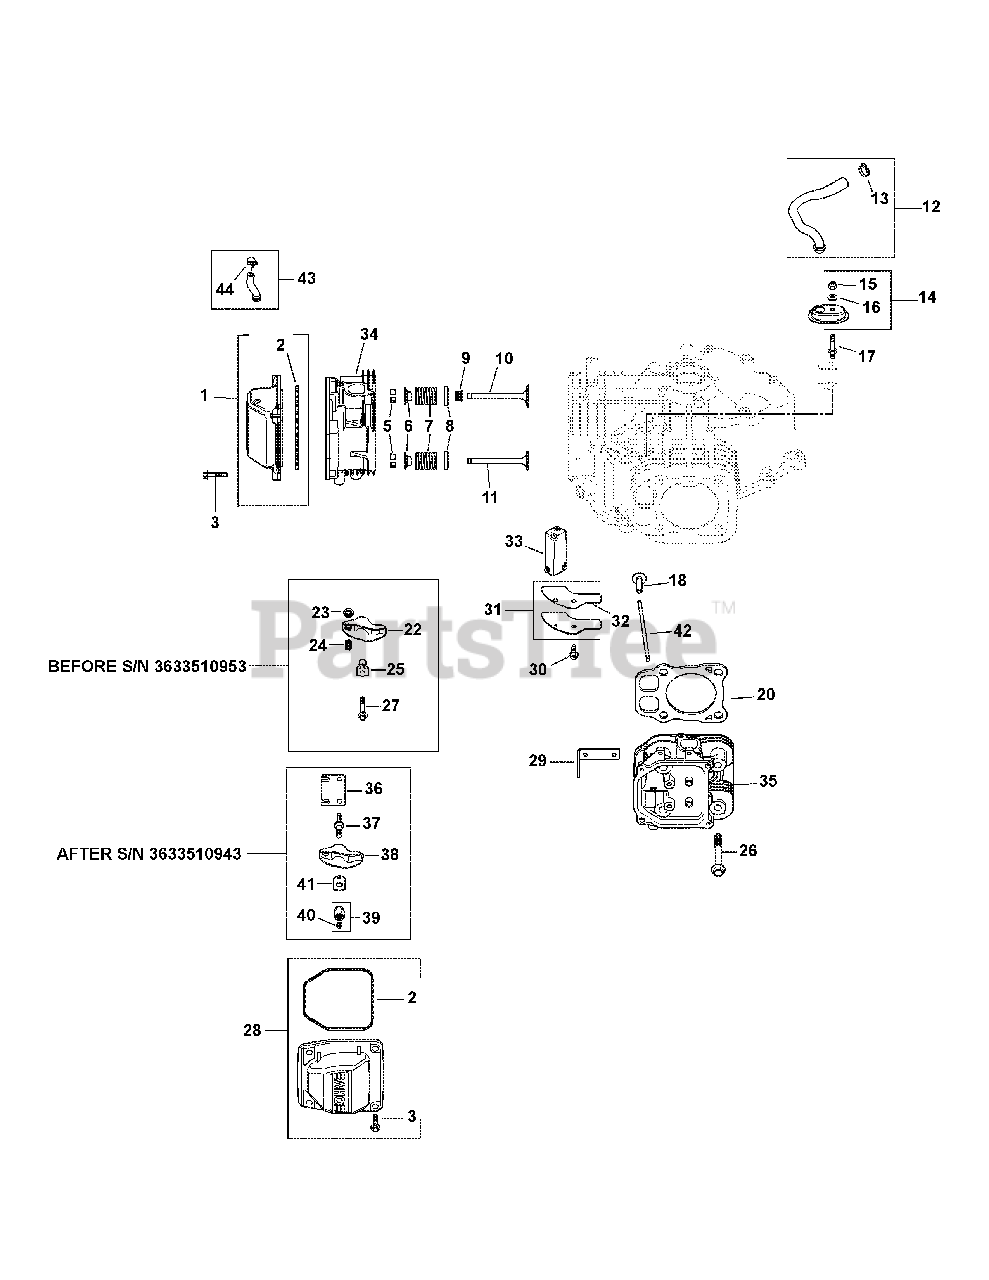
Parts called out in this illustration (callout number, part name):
1	Breather Valve Cover Kit
2	Valve Cover O-Ring
3	Flg. Screw, M6 x 1.0 x 30
6	Valve Spring Cap
8	Spring Retainer
9	Valve Stem Seal
11	Exhaust Valve
12	Breather Hose Kit
13	Hose Clamp, 1.2
14	Breather Housing Kit
15	Lock Nut, M5 x .8
16	Sealing Washer
17	Breather Cover Stud
20	Cylinder Head Gasket Kit
22	Fuse Block
23	Fuse Block
24	Fuse Block
25	Fuse Block
26	Flg. Screw, M10 x 1.5 x 90
27	Fuse Block
28	Breather Valve Cover Kit
29	Lifting Strap
30	Flg. Thd. Frm. Screw, M6 x 1.0 x 16
31	Breather Cover Kit
33	Breather Filter
34	#1 Cylinder Head Assembly Kit
35	#2 Cylinder Head Assembly Kit
39	Hex Nut Assembly
41	Rocker Arm Pivot
43	Fuel Pump Hose Kit w/Clamp
